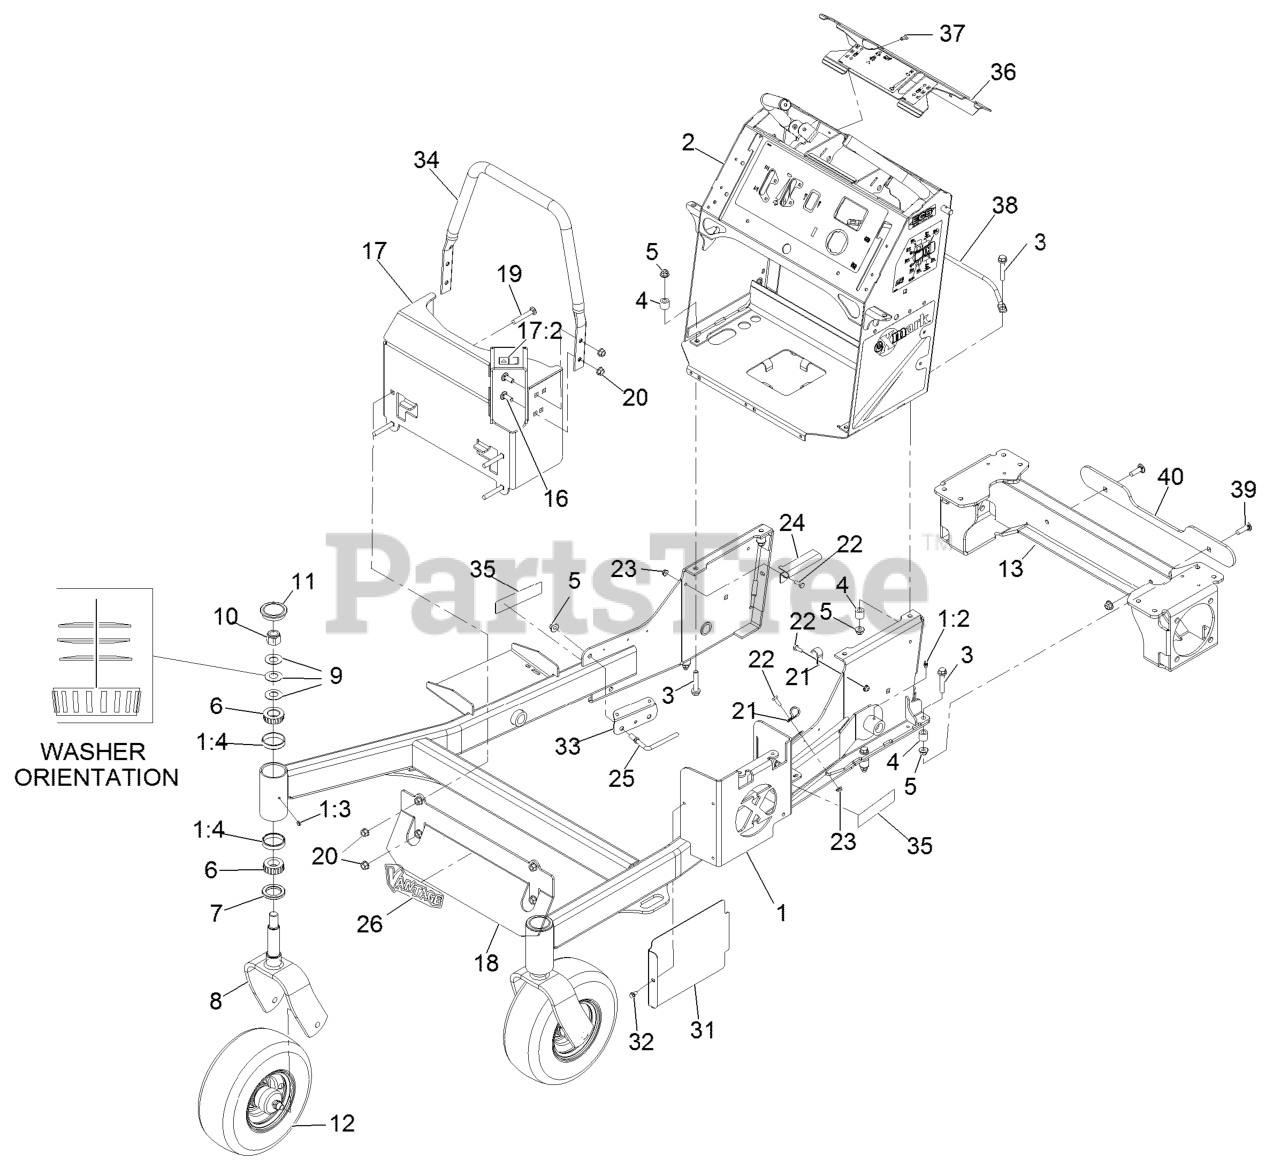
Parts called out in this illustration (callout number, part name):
1	FRONT FRAME ASM
1:2	FITTING-GREASE
1:4	CUP-BEARING
2	TOWER ASSEMBLY
3	SCREW-HHF
5	NUT-HF, NI
6	Cone-Bearing Tapered Roller
7	SEAL-GREASE
8	FORK-CASTER
9	WASHER-BELLVILLE
10	NUT-LOCK, NI
11	CAP-GREASE
12	WHEEL/TIRE AND BEARING AS
13	WELD, MOTOR FRAME
16	SCREW-CARR
17	ASM, MUFFLER GUARD W/ DEC
17:2	DECAL-WARNING
18	PANEL-GUARD
19	SCREW-CARR
21	CLAMP-CABLE
22	SCREW-HH
24	BRACKET-HOSE, FUEL
25	GUIDE-HOSE, SUPPORT
26	DECAL-VANTAGE LOGO
31	SHIELD-HEAT, TALL
32	SCREW-HWH
33	GUARD-HOSE
34	TUBE-GUARD
35	DECAL-X-SERIES
36	CONTROL PANEL W/DECALS
38	ROD, GUARD
39	SCREW-CARR
40	PLATE, BUMPER SPACER
